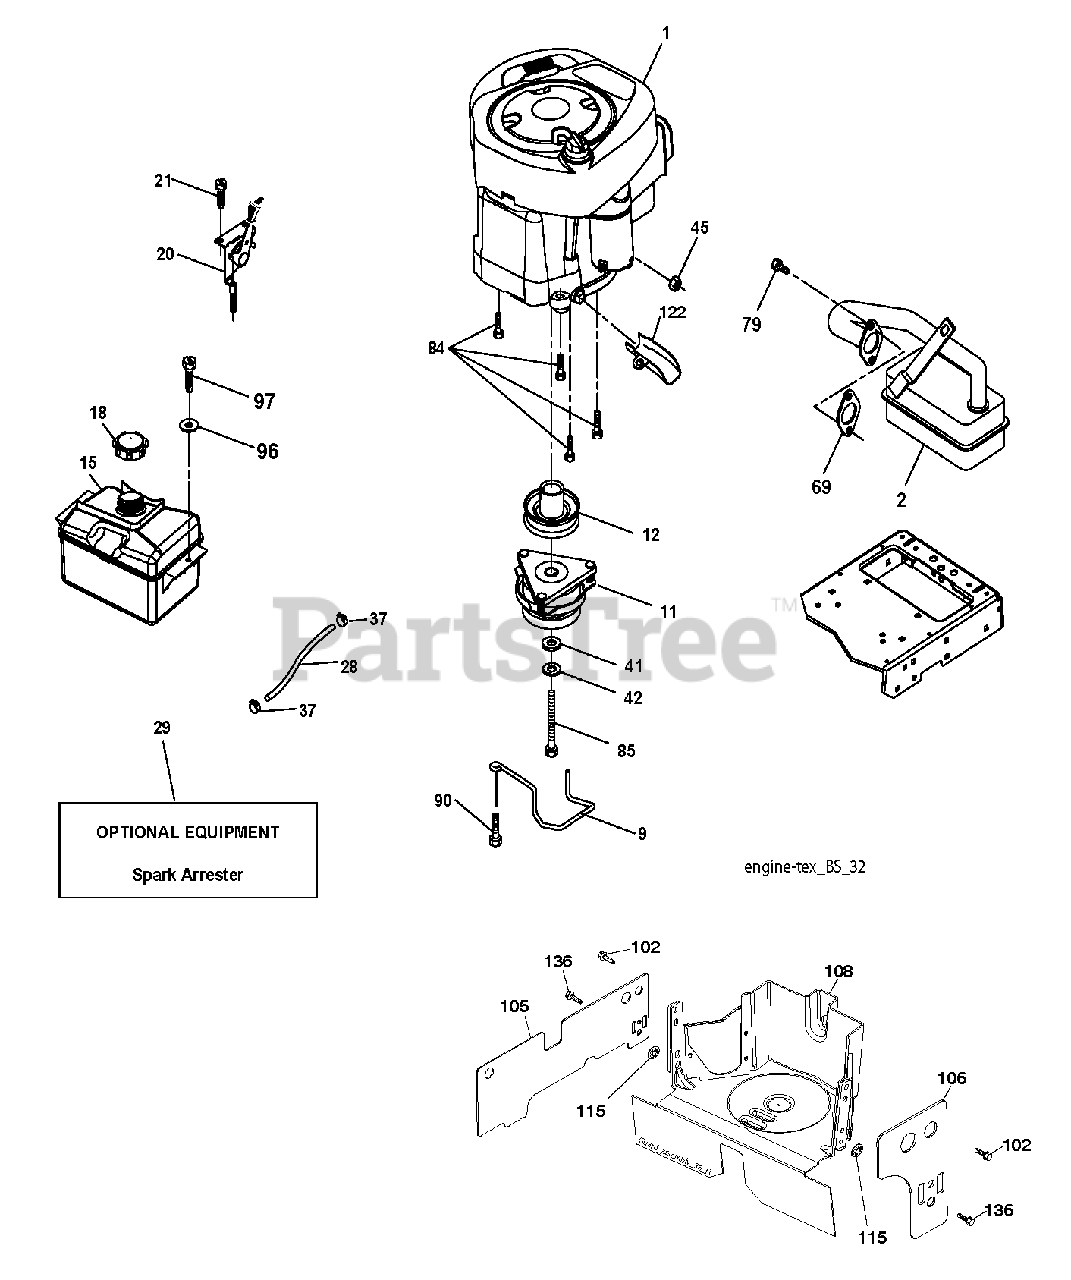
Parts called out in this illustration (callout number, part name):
2	MUFFLER.B&S.MODEL.21.11HP.OHV
9	KEEPER.BELT.ENGINE.3.25 (3 2)
11	RB.CLUTCH.OGURA.4.4.PD
12	PULLEY.ASM.ENG.OGURA.3
15	RP TANK FUEL FRT 1.5 GAL
18	CAP ASM.FUEL.2.25"FR.
20	CONTROL.TH/CK.C.
21	SCREW.#10 X 0.750.BOS
28	LINE.FUEL.20
29	KIT.SPARK ARRESTOR 794945 B&S
37	HOSE CLAMP
42	LOCKWASHER
45	NUT
69	REPL BY 532 27 22-93
79	SCREW.SOCKET HD.5/16-1
84	SCREW.3/8-16
85	BOLT HEX 7/16-20X4-1/4"
90	SCREW 3/8-16X1
97	SCREW HEXWSHR 1/4-20X3/4
102	SCREW
105	SHIELD LEFT
106	SHIELD SIDE
108	COVER PULLEY
115	PALNUT 1/4
122	EXTENSION DRAIN OIL
136	SCREW.1/4-20X5/8
